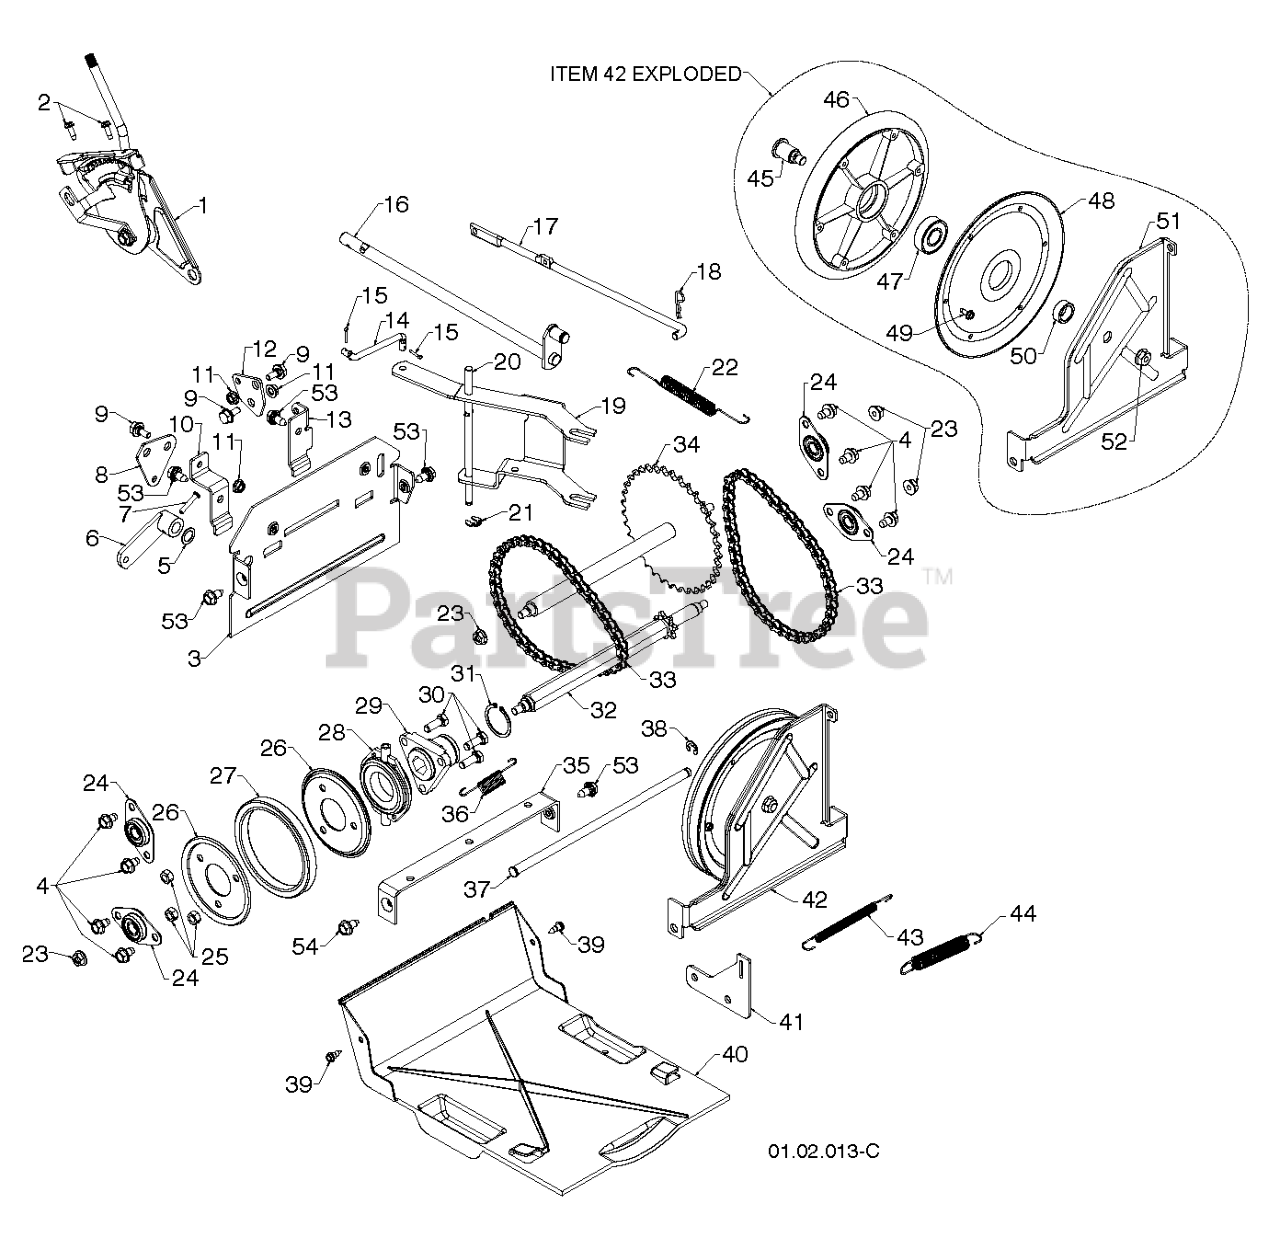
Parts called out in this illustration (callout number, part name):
1	HEAD ASSY SPEED
2	SCREW #10-24 X 5/8
3	PLATE.END.CHAIN.ASM.PNT.ORANGE
4	Screw 5/16-18 x 1/2 Hex, Self Tapping 5/16-18 x 1/2
5	THRUST WASHER
6	ARM, AUGER CONTROL
7	CLEVIS PIN
8	PLATE.SHIFTER.BZP
9	BOLT.SHOULDER.3/X.25
10	BRACKET.SHIFTER.PLATE.BZP
11	NUT.HEX.FLANGE.1/4
12	PLATE.CLUTCH.BZP
13	BRACKET.CLUTCH.PLATE.BZP
14	LINK, SPEED CONTROL
15	RETAINER CLIP
16	CONTROL.SHAFT.ASM
17	ROD.CLUTCH.SWING.PLATE
18	SPRING RETAINER
19	BRACKET.YOKE.SHIFTER.BLACK
20	ROD.PIVOT.SHIFTER
21	KLIP RING TI
22	SPRING.TRACTION.RETURN
23	NUT.LOCK.5/16-18
24	BEARING FLANGE BALL
25	NUT.CENTERLOCK.5/16-
26	PLATE.RUBBER.WHEEL
27	RING.RUBBER.2-STG.SNW.DRV.WH
28	TRUNNION BEARING ASSY
29	HUB, RUBBER WHEEL
30	BOLT
31	RETAINING RING (2 2)(3 2)
32	SHAFT.HEX.W/SPOCKET
33	CHAIN.DRIVE.SNOWTHROWER.#420
34	SPROCKET.WELDMENT
35	SHIFTER BRACKET
36	SPRING, BIAS
37	ROD.PIVOT.SWING.PLATE.SNOW
38	E-RING.RETAINER.REINFORCED.375
39	SCREW, HEX HEAD, TAPPING
40	PAN.BOTTOM.PLASTIC
41	BRACKET.TRACTION.SPRING.
42	RP.PULLEY.PLATE.ASM.DRIVE
43	SPRING.TRACTION.IDLER
44	SPRING, BRAKE
45	SHAFT.FRICTION.PULLEY.SNOW
46	PULLEY.PLATE.ASM.DRIVE
48	RP PULLEY.HALF.TRACTION
50	SPACER BEARING
51	PLATE.SWING.DRIVE.BLACK
52	FLANGED LOCKNUT 3/8-16 ZINC
53	BOLT.HEX.HD.WASHER.5/16-18X.75
54	BOLT.5/16HEX.WHS.HD
